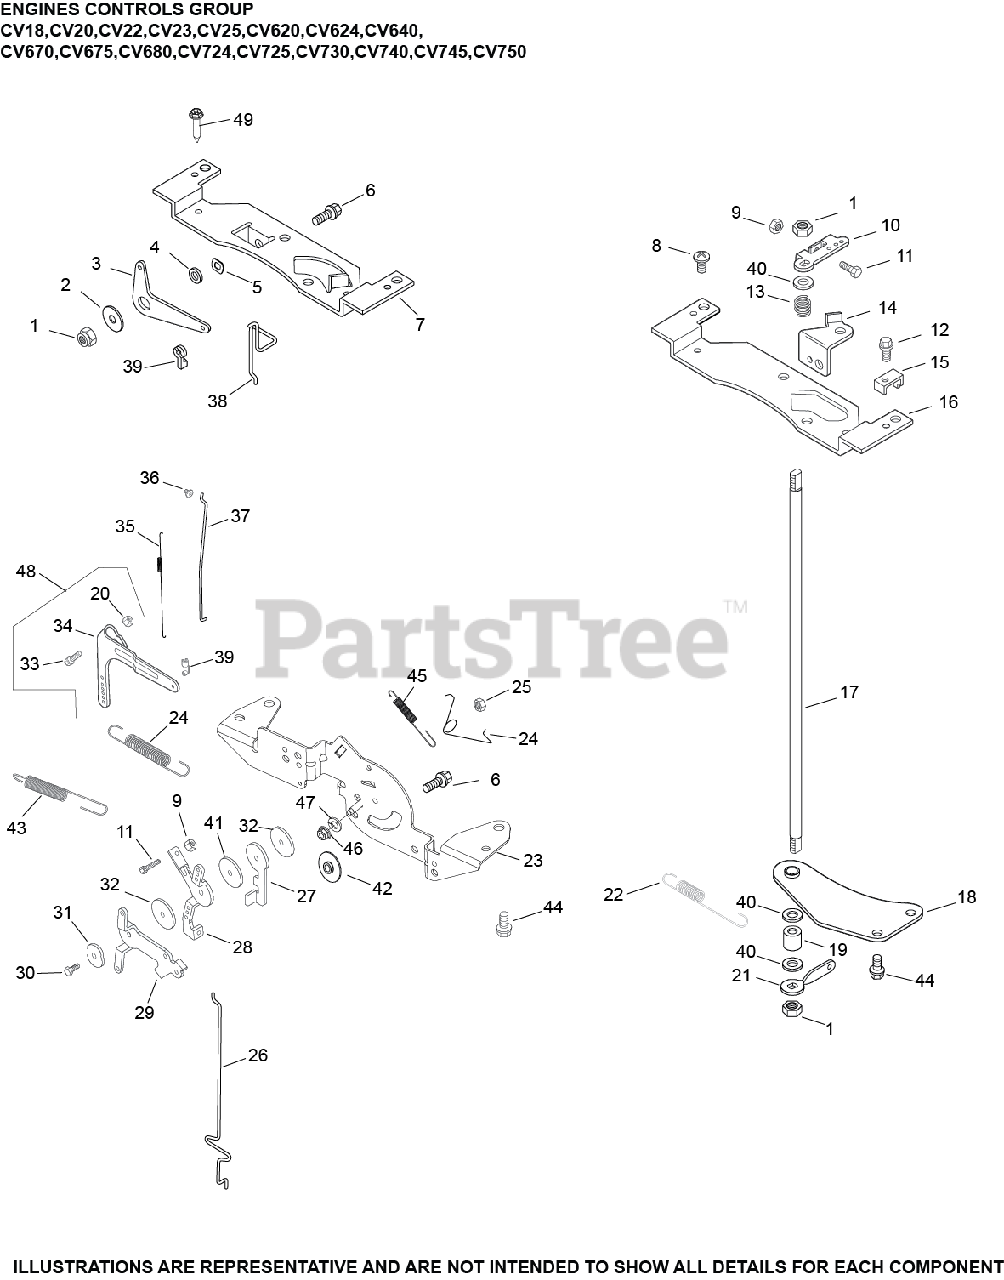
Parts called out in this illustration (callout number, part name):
1	NUT, LOCK M6X1.0
2	WASHER, FLAT 1/4"
3	LEVER, CHOKE
5	WASHER, SPRING 3/8"
6	SCREW, FLG M6X1.0X16
7	BRACKET, CONTROL
9	NUT, M4X0.7
10	LEVER, THROTTLE CONTROL
11	SCREW, CAP M4X.7X30
12	SCREW, THREAD FORMING
13	SPRING, THROTTLE SHAFT
15	CLAMP, CABLE
17	SHAFT, THROTTLE
18	BRACKET, THROTTLE SHAFT
20	NUT, FLG M6X1.0
21	LEVER, THROTTLE CONTROL
22	SPRING, GOVERNOR (ORANGE)
33	BOLT, RD HD SQ NECK M6X1.0X25
34	LEVER, GOVERNOR - (#2409069S)
35	SPRING, LINKAGE
36	BUSHING, LINKAGE RETAINING
37	LINKAGE, THROTTLE
38	LINKAGE, CHOKE
39	BUSHING, THROTTLE LINKAGE
40	WASHER, FLAT 1/4"
48	LEVER, GOVERNOR ASSEMBLY
49	SCREW, HEX WASHER HI-LO
